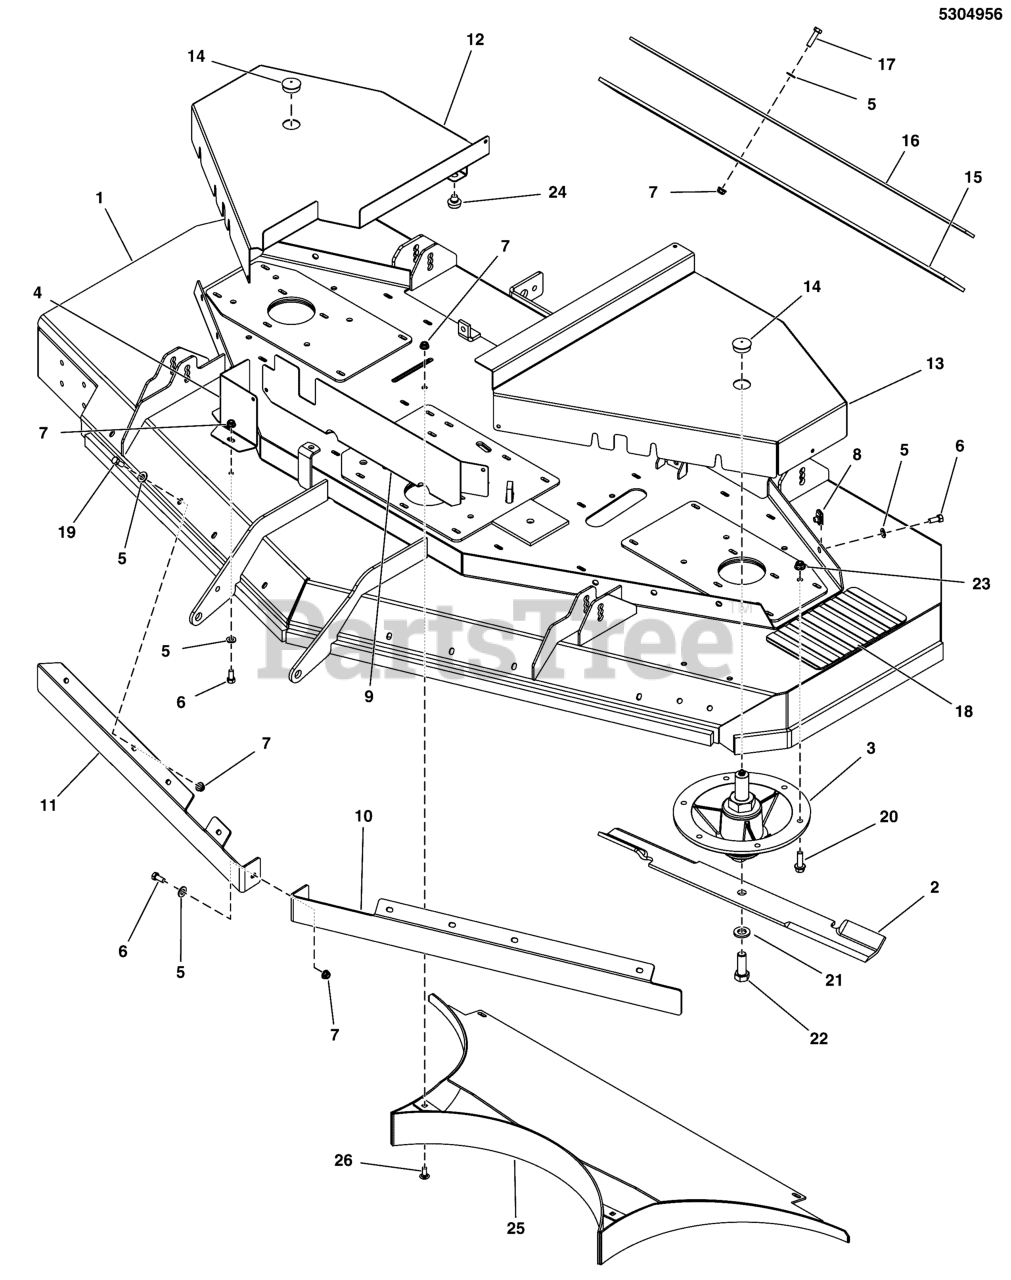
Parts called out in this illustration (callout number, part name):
1	DECK SHELL W/DECALS, 3200 72RDCE (5416028B)
1	DECK SHELL W/DECALS, 3200-72RE(5417030B)
2	BLADE SET, MULCH, 72 DECK (SET OF 3)
3	SPINDLE ASSEMBLY
4	PLATE, FRONT DECK GUARD, 72CE - RED
5	WASHER, 5/16" SAE
6	BOLT, 5/16-18 X 3/4 GD5
7	NUT, 5/16-18 HEX NYLOCK FLANGE NUT
8	BODY CLIP, 5/16-18-7GA MATERIAL
9	PLATE, FRONT DECK GUARD CE - RED
9	PLATE, FRONT GUARD, DECK-72CE - RED
10	PLATE, BLOWOUT BAFFLE IS5100Z CE, LH - RED
11	PLATE, BLOWOUT BAFFLE IS5100Z CE, RH - RED
12	GUARD, MOWER DECK, RH, 72 CE - RED
13	GUARD, CUTTER DECK, LH, 72 CE - RED
13	GUARD, DECK-LH, 72 2-BELT - RED
14	PLUG, PANEL, 1.25 - BLACK
15	FLAP, REAR DISCHARGE, 72"
16	PLATE, RUBBER SUPPORT, 72RD - RED
17	BOLT, 5/16-18 X 1-1/4" GD5 YZ
18	SAFETY WALK, 9.75 X 6.00
19	BOLT, 5/16-18 X 1" GRD5 YZ
20	BOLT, 3/8-16 X 1-1/4, FLANGE, GD 5, CZ
21	WASHER, BLADE BOLT, 9/16" F436, CZ
22	BOLT, 5/8-11 X 1-3/4 GD8
23	NUT, 3/8 - 16 HEX NYLOCK FLANGE
24	MNT, VBRTN, RBBR
25	WELD, REAR BAFFLE, 72RD SHORT - RED
26	BOLT, 5/16-18 X 3/4, CARRIAGE, GD5, CZ
